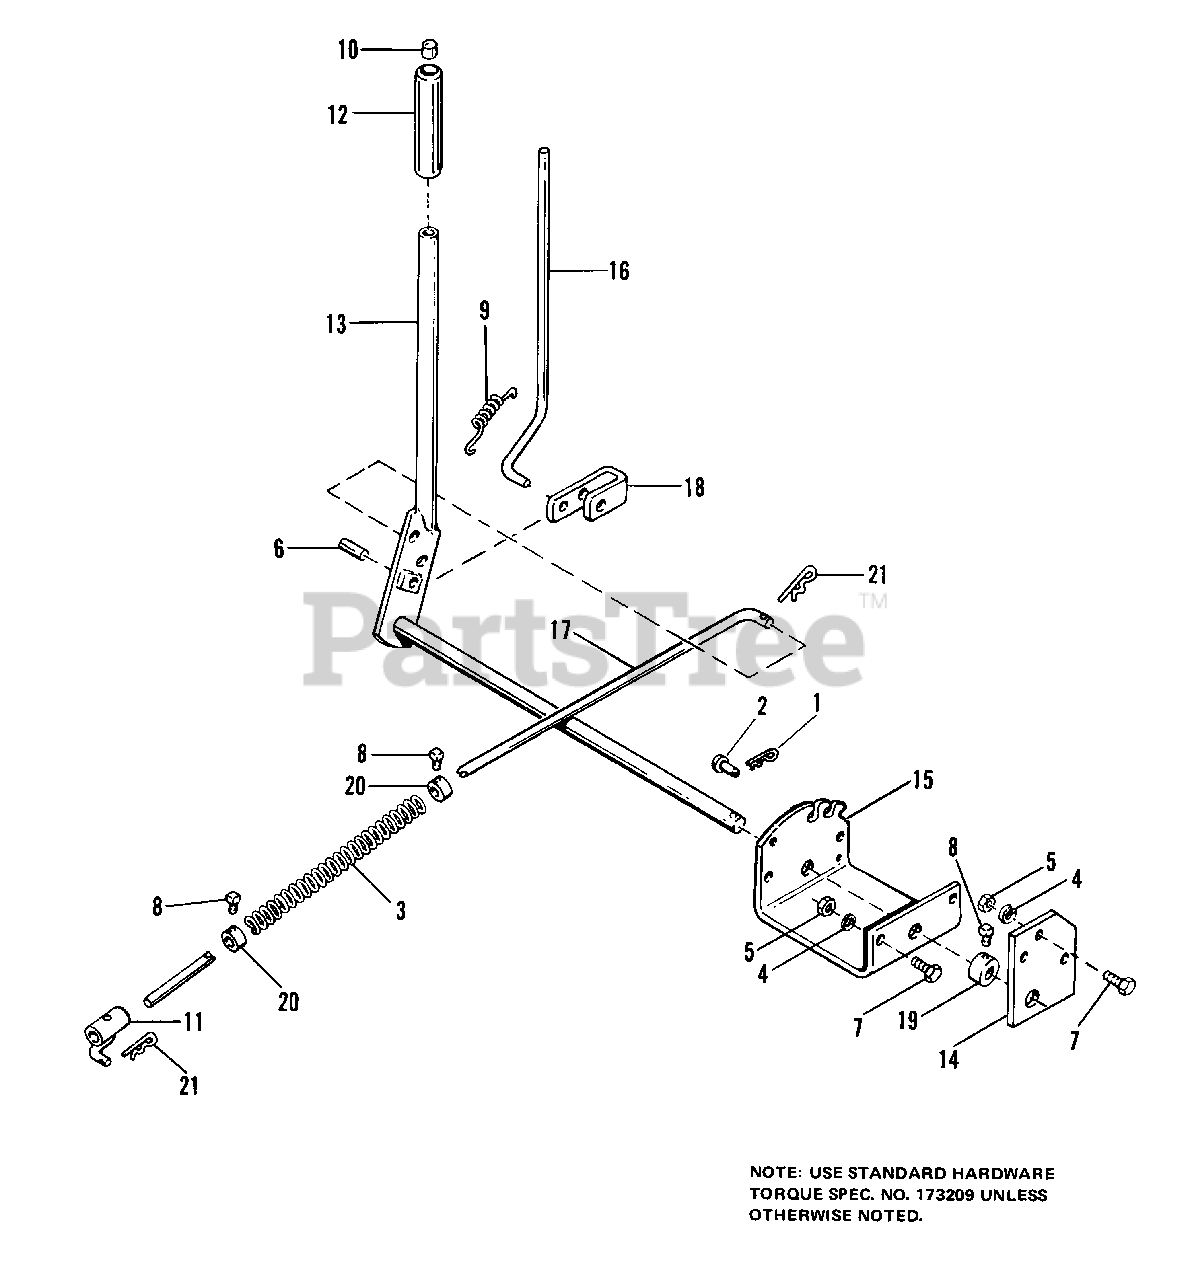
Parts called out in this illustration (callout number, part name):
1	CLIP, Spring
4	LOCKWASHER, Spring, 5/16
5	NUT, Hex, 5/16-18
6	PIN, Spring, 3/8 x 1
7	CAPSCREW, Hex, 5/16-18 x 3/4
8	SCREW, Set, Sq. Hd., 5/16-18 x 3/8
11	GUIDE ASSY, Rod
12	GRIP, Lift Lever
13	LEVER ASSY, Lift
14	SUPPORT, Shaft
15	QUADRANT, Lift
16	ROD, Latch
17	ROD, Lift
18	LATCH, Lever
19	COLLAR, Set
20	COLLAR, Set
21	CLIP, Hair Pin
